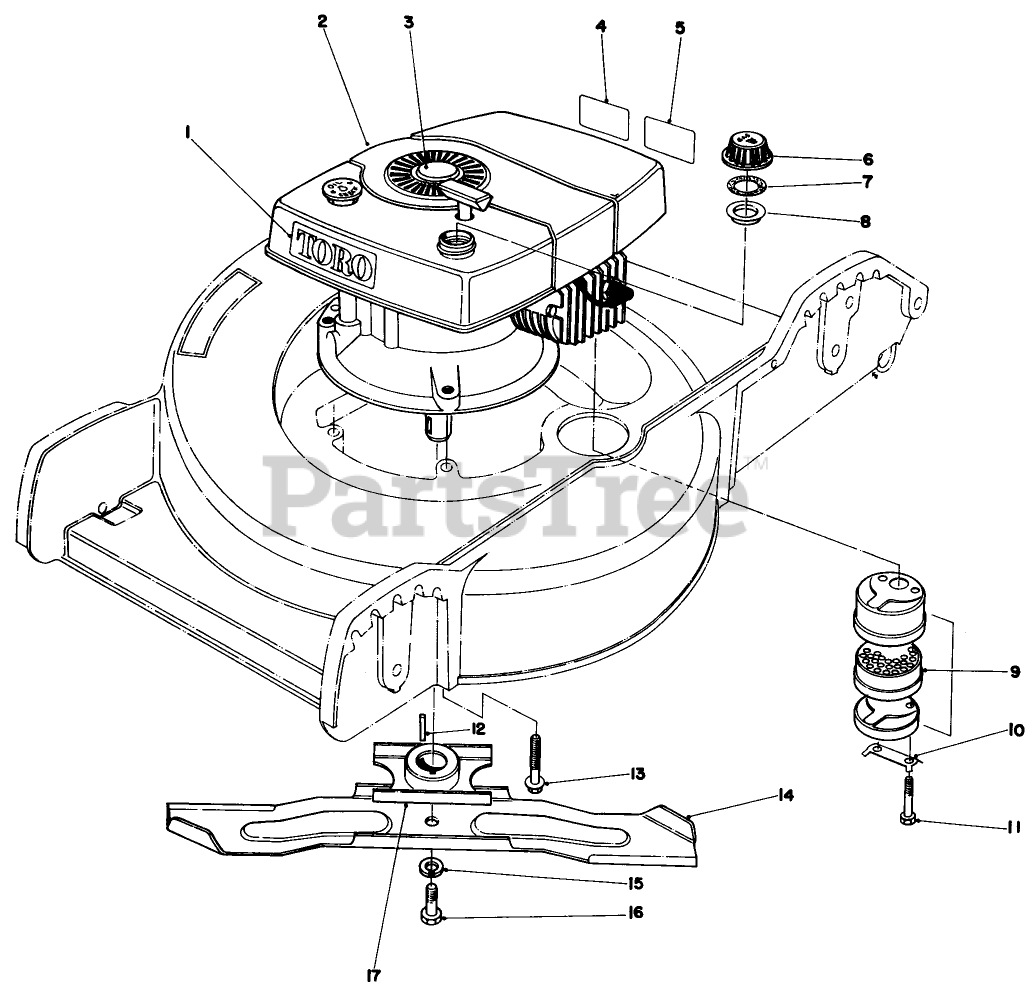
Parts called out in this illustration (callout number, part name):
1	Decal Toro
2	Engine
3	Plug Button
4	Decal-Maintenan
5	Decal Maintenance
6	Gas Cap (Incl. Ref. #7 & 8)
7	GASKET
8	GAS CAP BAFFLE
9	Muffler Assembly (Incl. Ref. #10 & 11)
10	CLIP - LOCKING
11	SCREW-HH
12	KEY-SQUARE
13	3/8-16 X 2 CAPSCREW
14	Blade
15	WASHER-LOCK
16	SPECIAL SCREW
17	Blade Retailer
